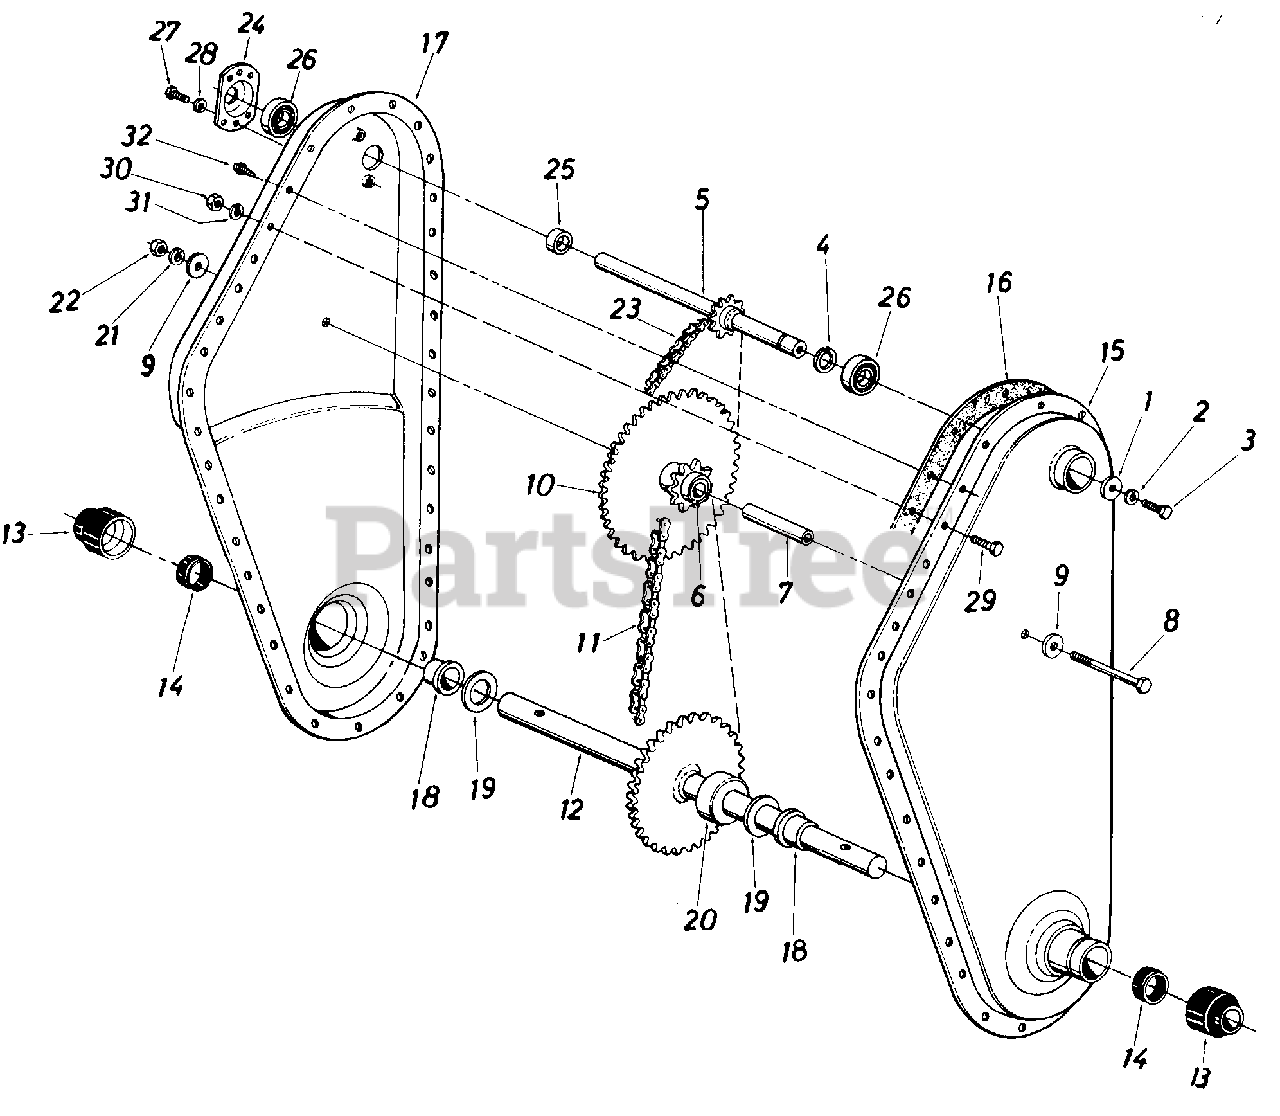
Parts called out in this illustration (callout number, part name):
1	Fl-Wash. 1/4" I.D. x .93n O.D. x .1 20
2	L-Wash. 1/4" I.D.
3	Hex Bolt 1/4-28 x .62n Lg. w/ Patch
4	External Snap Ring-5/8" Dia.
5	Input Shaft Ass'y.
6	Bearing 5/8" I.D. x 3/4" O.D. x 1.860" Lg.
7	Sprocket Hub Tubing 5/8" I.D. x 5/8" O.D. x 1.90
8	Hex Bolt 3/8-24 x 2.75 Lg.
9	Fl-Wash. 818" I.D. x 1.25" O.D. x .10
10	Sprocket Ass'y.
11	#50 Chain 5/8" Pitch x 46 Links Endless
12	Tine Shaft Ass'y.
13	Dust Cup
14	Seal Ring Single Lip, Springless
19	Fl-Thrust Wash. 1.0" I.D. x .03 Thk.
20	Step Spacer
21	L-Wash. 3/8" I.D.
22	H ex Nut 3/8-24 Thd .
23	#35 Chain 3/8" Pitch x 52 Links Endless
24	Bearing Housing 1.38" I.D.
25	Spacer
26	Ball Bearing .625" I.D. x 1.38" 0 D. x .437
27	Hex Wash. SF-Tap Scr. 1/4-20 x 50" Lg
28	L-Wash. 1/4" I.D.
29	Hex Bolt 5/16-18 x .75" Lg.
30	Hex Nut 5/16-18 Thd.
31	L-Wash. 5/16" I.D.
32	Hex Wash. SF-Tap Scr. 1/4-20 x.50" Lg.
